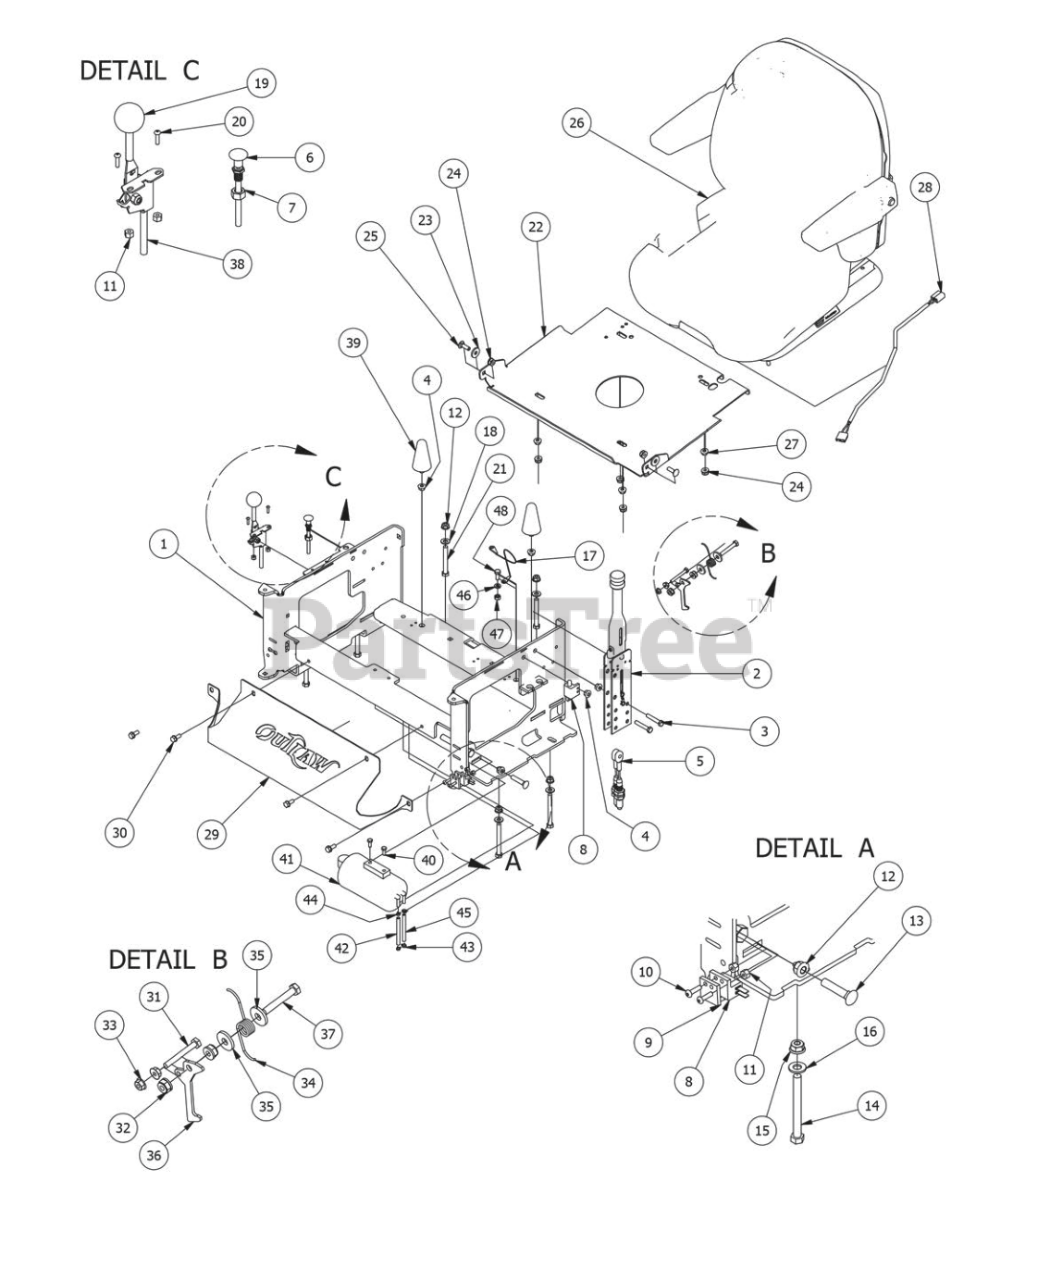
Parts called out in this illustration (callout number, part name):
1	Outlaw Seat Bracket 2012
2	Brake Handle Kit
3	5/16" x 1 3/4" Hex Bolt
4	5/16" Nylon Flange Nut
5	Long Brake Cable
7	3/8" Fine Threaded Jam Nut
8	Safety Switch
9	Switch Block Plastic
10	10-24 x 1 BS C/S 18-8 SS
11	10-24 Nylon Insert Locknut
12	3/8" Nylock Flange Nut
13	3/8 x 1 3/4 Carriage Bolt
14	3/8-16x3-1/2 grade 5 hex bolt
15	3/8" Nylock Flange Nut
16	3/8" Flat Washer
17	Seat Cable
18	3/8" Flat Washer
19	Universal Throttle Head - 2012
20	10-24 X 5/8 BS C/S 18-8 SS
21	3/8-16x3 grade 5 hex bolt
22	Seat Plate
23	.360 ID Plastic Washer
24	5/16-18 Nylon Flange Nut
25	5/16" x 1" Carriage Bolt
26	2010 Outlaw Seat
27	5/16" Flange Nut
28	Seat Switch Adapter
29	Outlaw Cooler Cover
30	5/16 x 3/4 washer head type F screw
31	1/4-20 x 2 Hex Bolt
32	5/16-18 Nylon Flange Nut
33	1/4-20 Hex Flange Nuts Zinc w/Serrations
34	Torsion Spring for Seat latch
35	.360 ID Plastic Washer
36	Seat Latch Lever
37	5/16-18 X 2 Hex C/S (GR.5) ZC
38	Outlaw Throttle Cable Only
39	Rubber Cone-1621-153
40	M6-1.0 X 16MM Hex Bolt
41	Carbon Canister ZT,CZT,Outlaw
42	3/16 vinyl tubing
43	3/16 vinyl clamp
44	3/16" Vinyl Hose Clamp
45	1/4" vinyl tubing
46	5/16" Lock Washer
48	5/16" x 3/4" Hex Bolt
